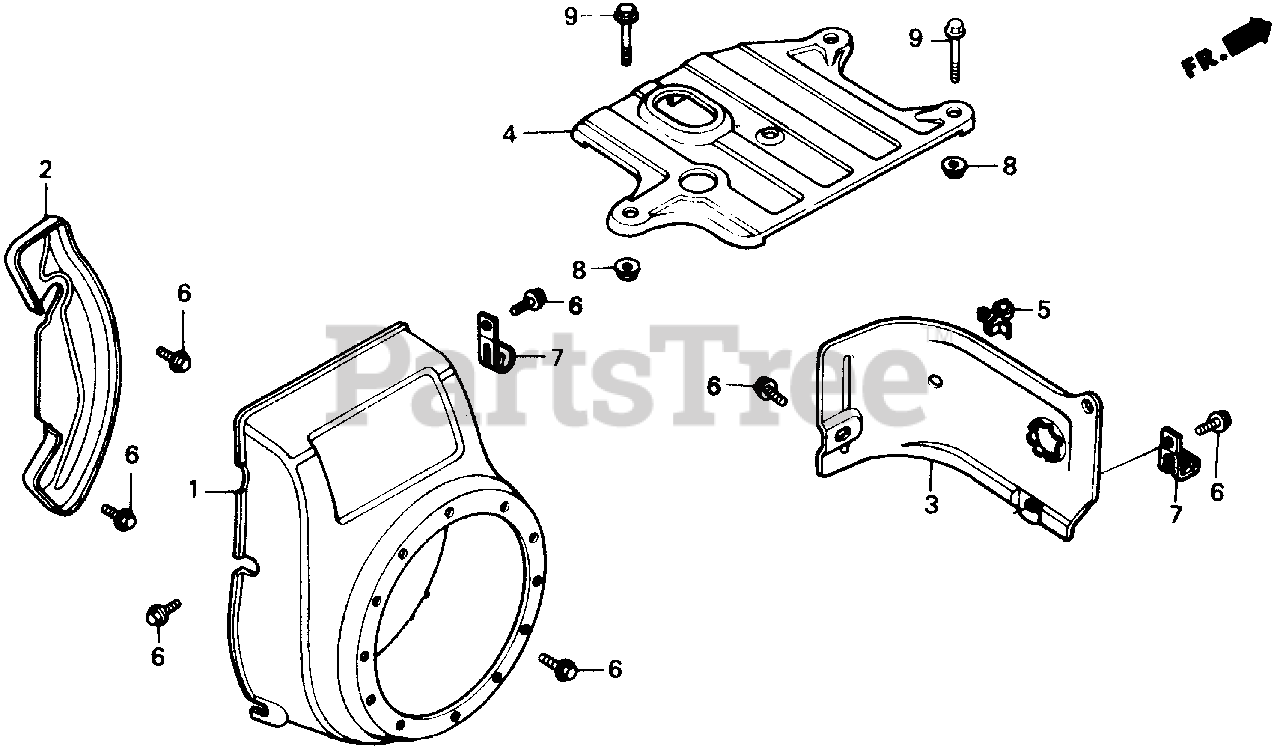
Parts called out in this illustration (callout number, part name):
1	COVER, FAN *R8* (BRIGHT RED)
2	PLATE, SIDE
4	COVER, TOP
5	CLIP, IGNITION WIRE (8MM)
6	BOLT, FLANGE (6X12) (CT200)
7	CLIP, CABLE
8	NUT, FLANGE (6MM)
9	BOLT, FLANGE (6X28)
